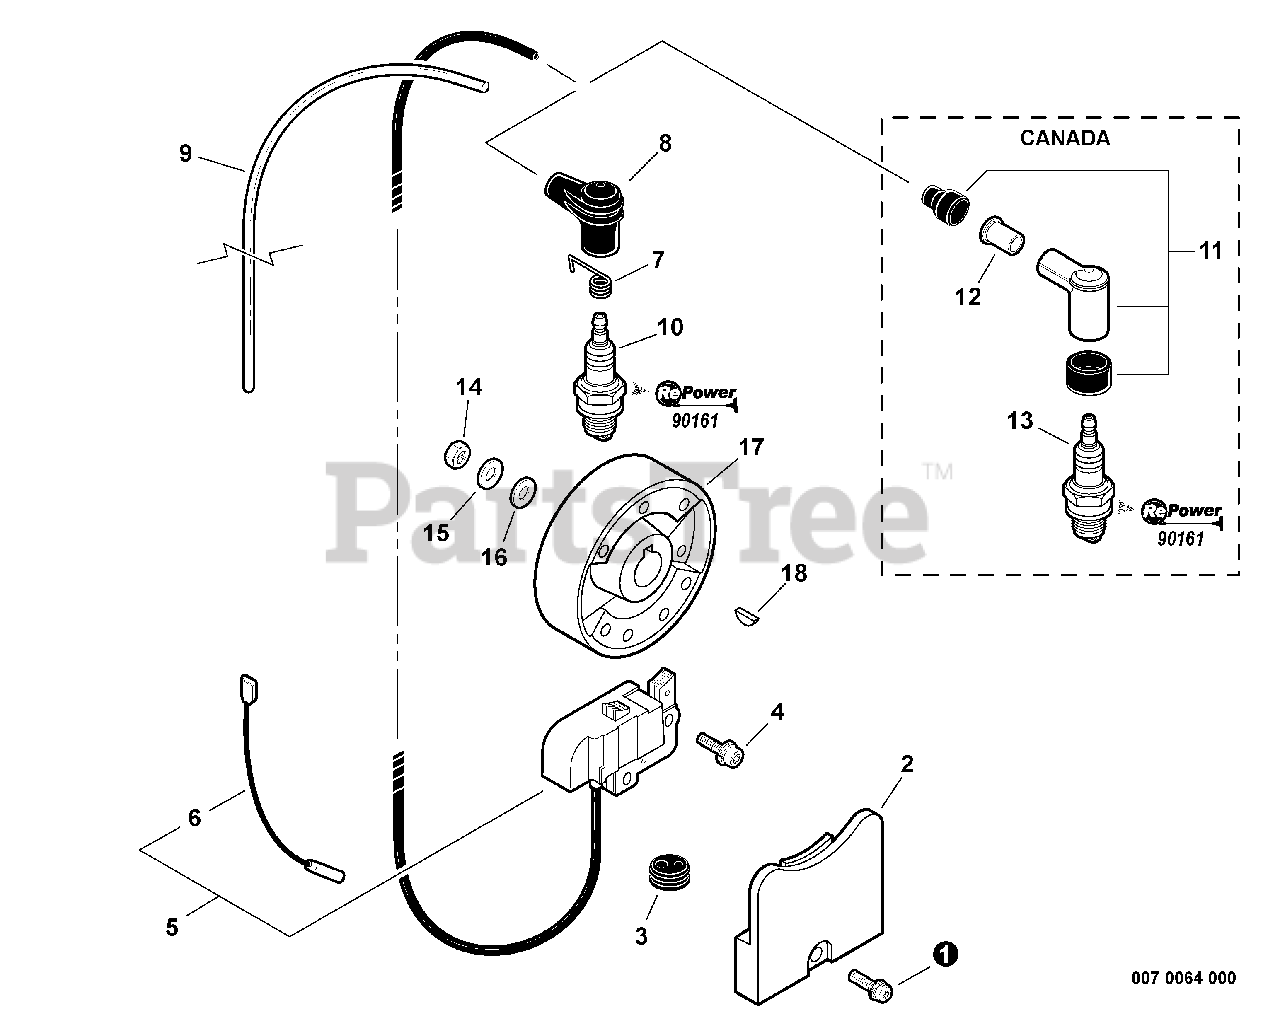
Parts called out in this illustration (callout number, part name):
1	SCREW 5×18
2	COVER, DUST
4	SCREW 5×18
5	COIL, IGNITION
6	LEAD - GROUND
7	TERMINAL, SPARK PLUG
8	CAP, SPARK PLUG
9	TUBE, VINYL 6.3×8×380
10	SPARK PLUG - BPM8Y
11	CAP, SPARK PLUG
12	ADAPTOR, SPARK PLUG - CAP
13	SPARK PLUG - BPMR8Y
15	WASHER, SPRING 10
16	WASHER, SPRING 10
17	FLYWHEEL
18	KEY, WOODRUFF 3×14
19	TUNE-UP KIT - REPOWER
